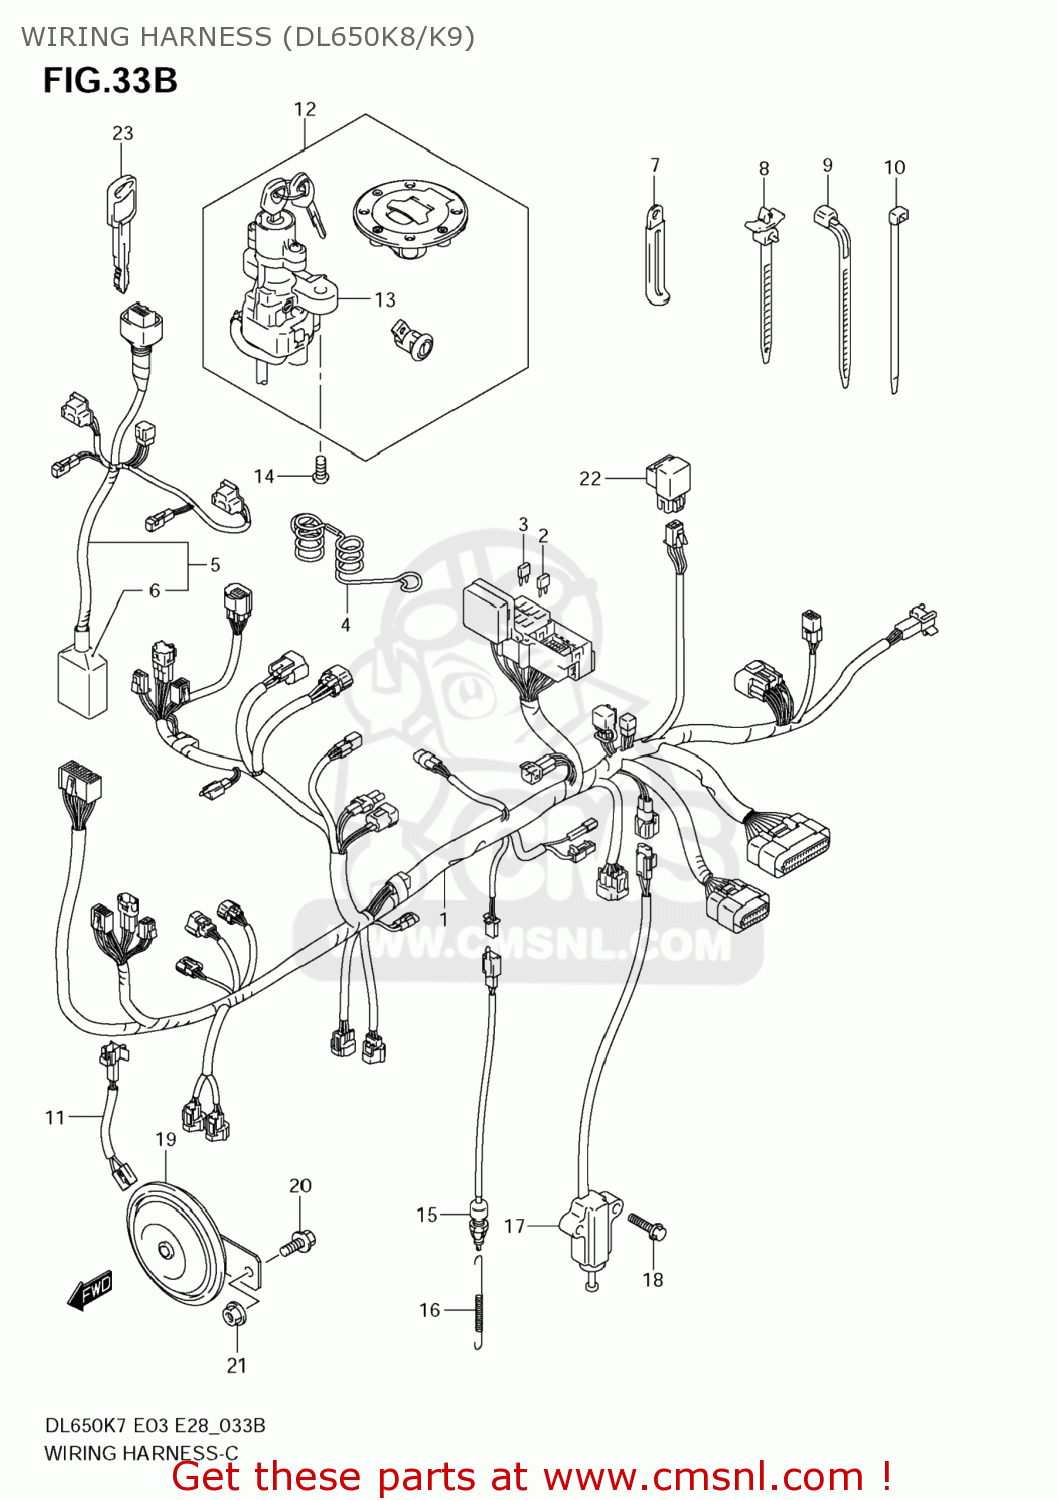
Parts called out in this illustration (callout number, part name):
1	HARNESS,WIRING NO.1
2	FUSE(10A)
3	FUSE(15A)
4	GUIDE,WIRING HARNESS
5	HARNESS,WIRING NO.2
6	COVER,CONNECTOR
7	CLAMP(L:45)
8	CLAMP(L:120)
9	CLAMP(L:95)
10	CLAMP(L:145)
11	WIRE,HORN LEAD
12	LOCK SET
13	LOCK ASSY,STEERING
14	BOLT(8X20)
15	SWITCH ASSY,STOP LAMP
16	SPRING
17	SWITCH ASSY,SIDE STAND
18	BOLT
19	HORN ASSY
20	BOLT
21	NUT
22	RELAY ASSY
23	KEY,BLANK
